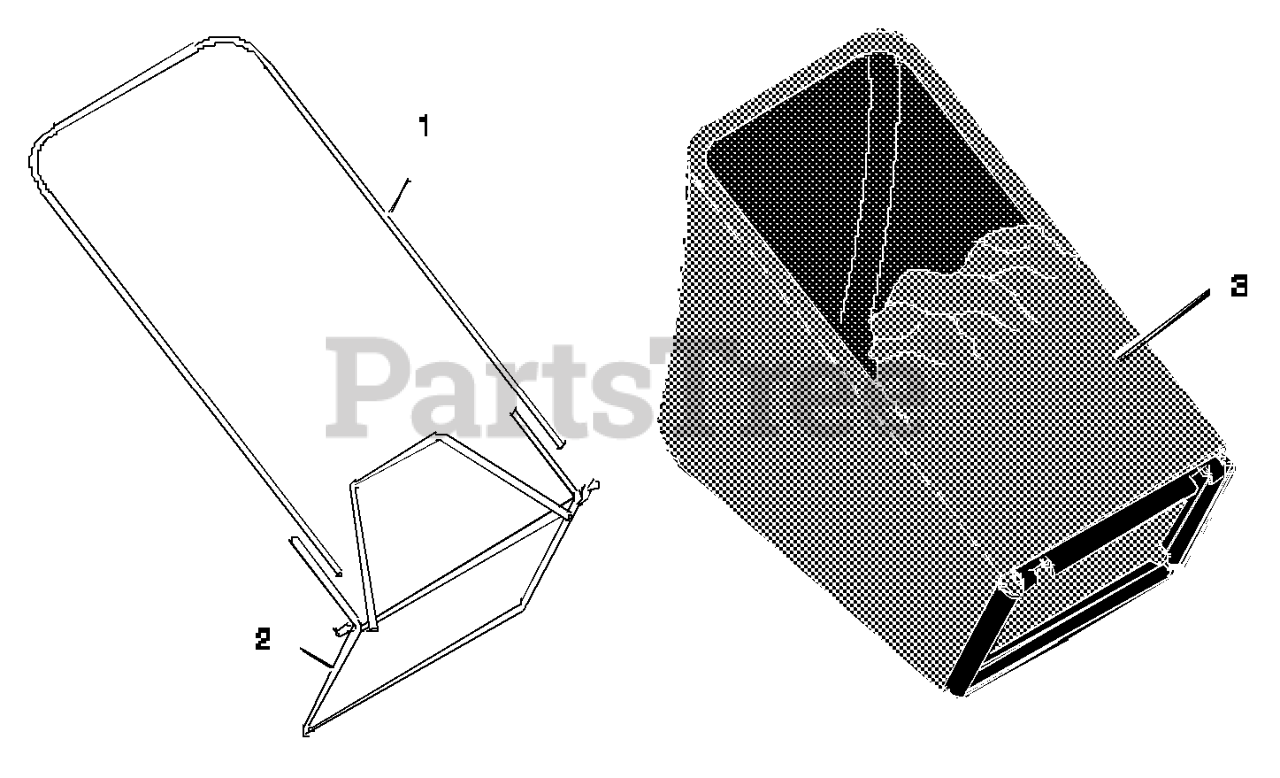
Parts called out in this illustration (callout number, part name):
1	Frame, Top
2	Frame Assembly
3	Bag, Cloth
